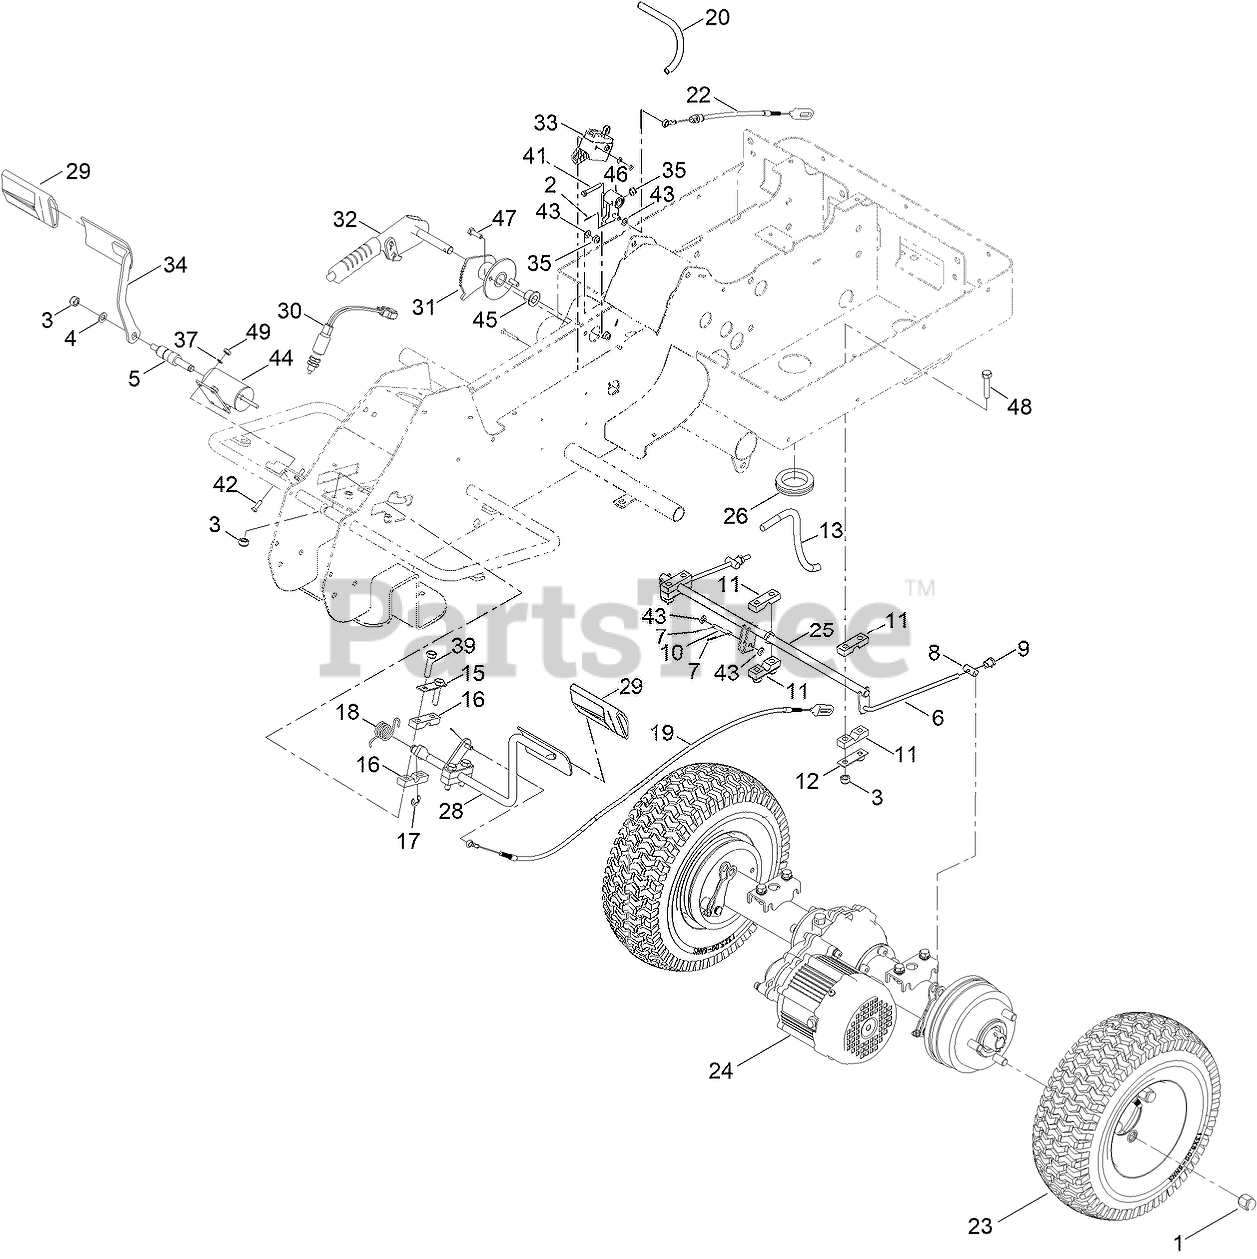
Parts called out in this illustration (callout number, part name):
2	BOBBY PIN
3	NUT-HEX, NI
4	WASHER
5	SHAFT, THROTTLE
6	ROD, BRAKE CONNECTION
7	BOBBY PIN
8	PIN, BRAKE CONNECTION (FLAT)
9	NUT , BRAKE ADJUSTMENT
10	PIN, BRAKE CABLE
11	MOUNTING, BRAKE ROD
12	PLATE, BRAKE MOUTING
13	COVER, WIRE
15	PLATE, PEDAL MOUTING
16	BLOCK, PEDAL HOLDER
17	CLIP, PEDAL HOLDER
18	SPRING, PEDAL
19	CABLE, PEDAL BRAKE
20	COVER, WIRE
22	CABLE, HAND BRAKE
23	REAR WHEEL ASM
24	TRANSMISSION ASSEMBLY
25	REAR TRANSISION ASM
26	INSERT, WIRE (SMALL)
28	BRAKE PEDAL ASM
29	COVER, PEDAL
30	BRAKING SWITCH ASM
31	HAND BRAKE, HUB ASM
32	HAND BRAKE, HANDLE ASM
33	SWITCH ASM
34	PEDAL, LEFT
35	NUT-NYLOC
37	WASHER
39	BOLT
42	SCREW-HH
43	WASHER-PLAIN
44	HUB ASM, THROTTLE
45	BUSHING, PARKING BRAKE
46	ASM, SWITCH PIVOT
47	SCREW-HH
48	BOLT
